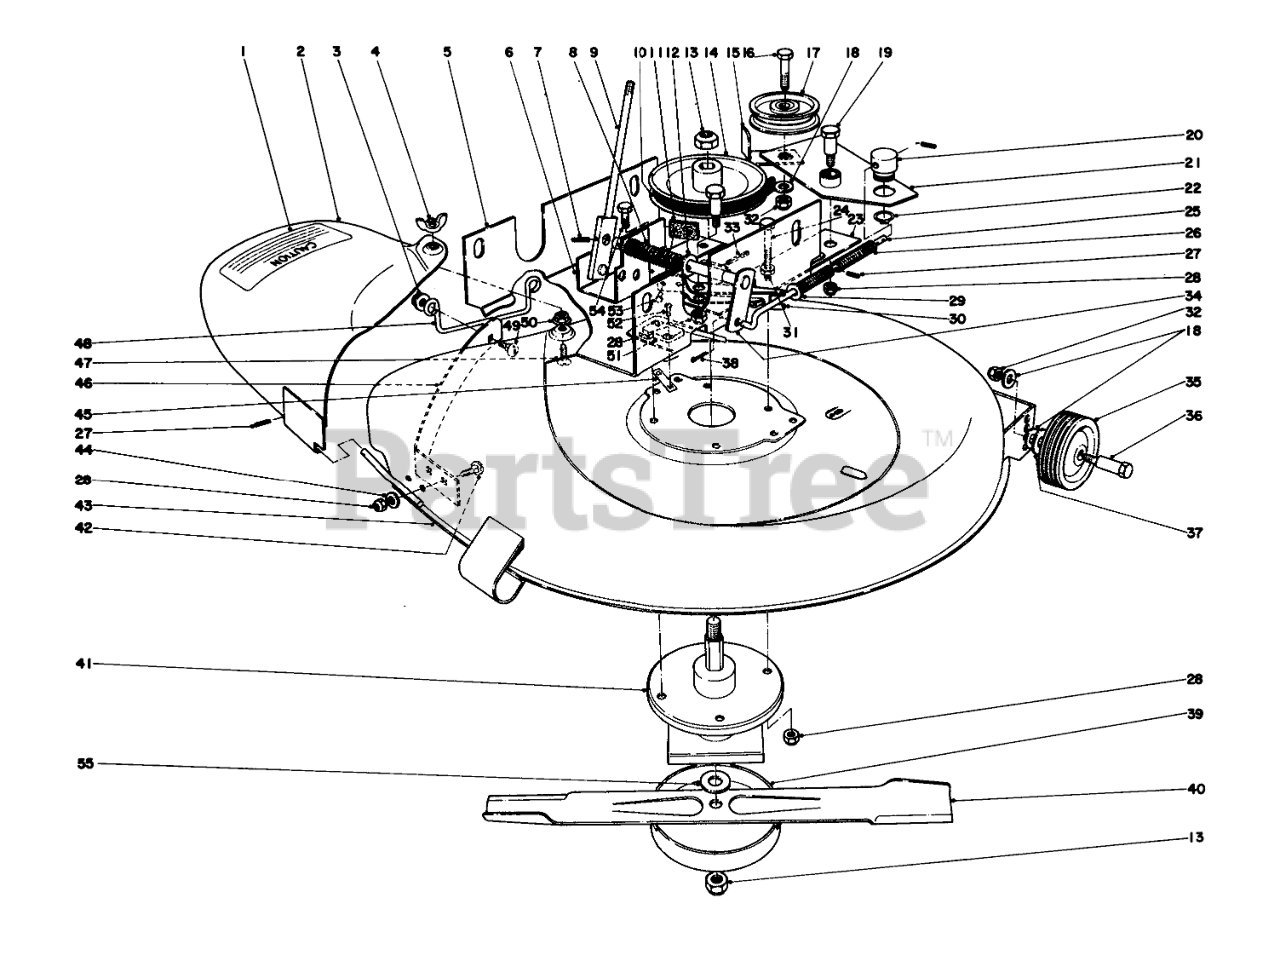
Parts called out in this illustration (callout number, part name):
1	Decal
2	Deflector
3	NUT-LOCK, HHF
4	Wing Nut
5	CHANNEL HT ADJ R
6	Mounting Bracket Blade
7	PIN-SPRING
8	COMP SPRING O
9	Deck Engagement Lever
10	V-Belt
11	BLADE BRAKE LINING
12	WASHER-FLAT
14	Pulley
15	Belt Retainer
16	SCREW-HH
17	Flat Idler
18	WASHER-FLAT
19	CLUTCH PIVOT BOLT
20	Pivot Pin
21	Idler Arm
22	RING-RETAINING
23	Bracket Idler Mounting
24	SCREW-HH
25	Blade Engage Rod
26	DECK IDLER SPRING
27	PIN-SPRING
28	NUT-LOCK, CONE
29	WASHER
30	Blade Brake
31	NUT-JAM
32	NUT-LOCK, CONE
33	PIN-SPRING
34	Linkage
35	Wheel
36	Axle Bolt
37	WASHER-FLAT
38	PIN-COTTER
39	Cup
40	Blade
41	Mower Spindle
42	BOLT-CARR
43	Housing
44	WASHER-FLAT
45	NUT-SPEED
46	Bar-Deflector
47	Flat Head Screw
48	Bracket Foot Guard
49	SCREW-CARRIAGE
50	PAL NUT
51	MICRO SWITCH
52	SCREW-SPH
53	Rivet
54	SCREW-HH
55	WASHER
